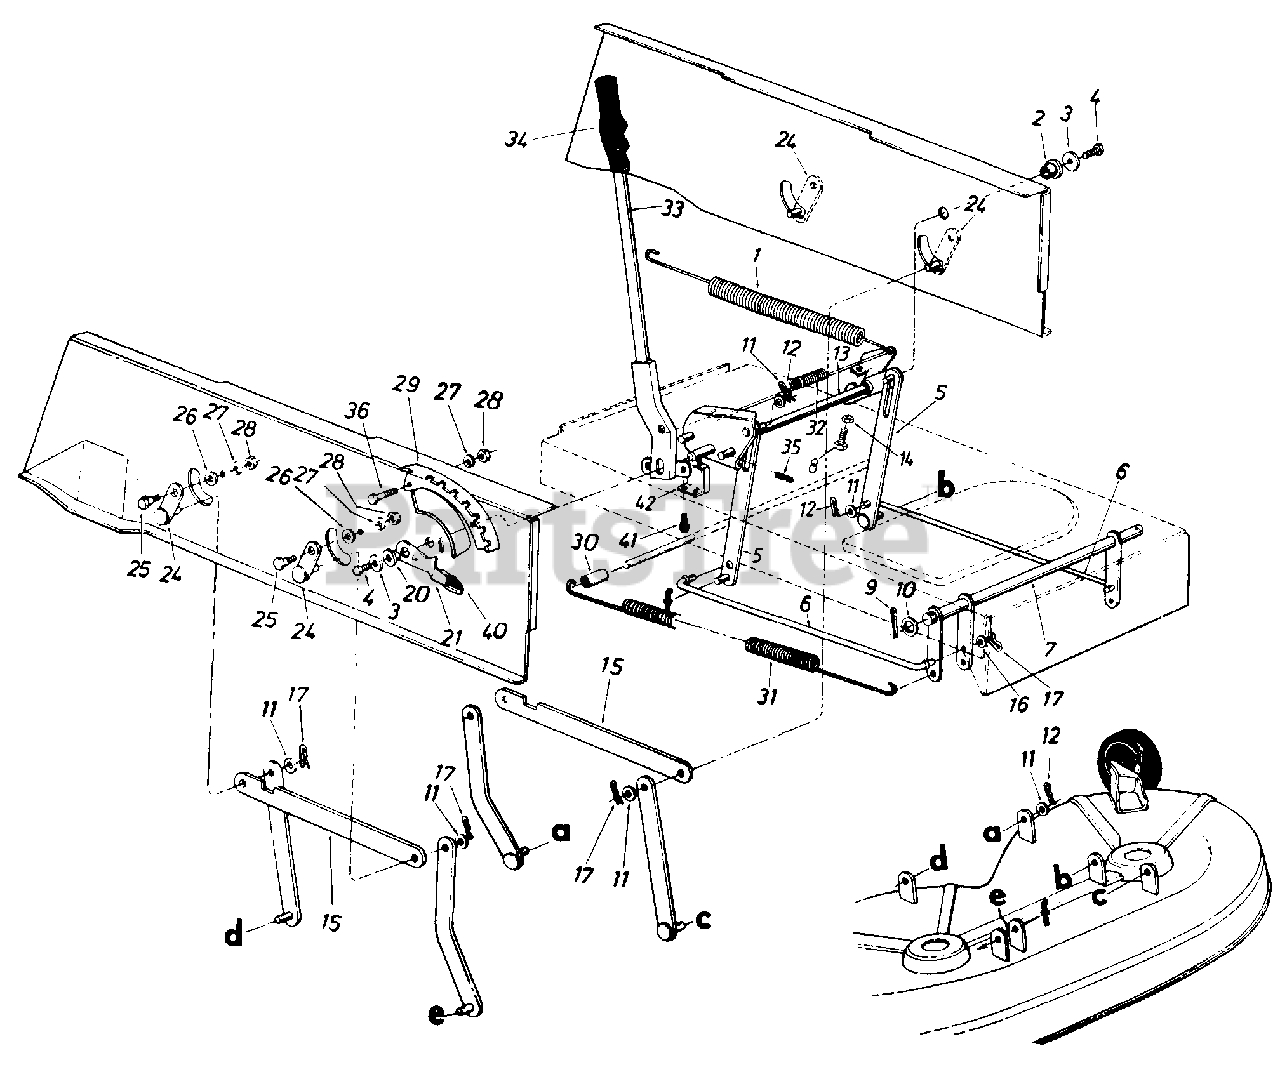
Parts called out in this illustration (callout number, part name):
1	Extension Spring 11" Lg.
2	Flange Bearing 634" I.D.
3	Fl-Wash. .344" I.D. x 1.125"
4	Hex Wash. Hd. 5/16-18 x .62" Lg.
5	Link Deck Lift Ass'y.
6	Stabilizer Rod
7	Stabilizer Shaft Ass'y.
8	Hex Tap Scr. 5/16-18 x 1
9	Cotter Pin 1/8" Dia. x 11/4"
10	Fl-Wash. .635" I.D. x 1.12
11	Fl-Wash. .531" I.D. x .940"
12	Inter. Cotter Pin
13	Lift Shaft Ass'y.
14	Hex Jam Nut 5/16-18 Thd.
15	Connecting Rod
16	Fl-Wash. .40" I.D. x .88"
17	Inter. Cotter Pin-3/8" Rod
20	Flange Brg. .630" I.D.
21	Deck Lift-Down Stop
24	Pivot Link Ass'y.
25	Shld. Bolt .437" Dia. x .180" Lg. (5/16-18)
26	Fl-Wash. .344" I.D. x .62"
27	L-Wash. 5/16" I.D.
28	Hex Nut 5/16-18 Thd.
29	Index Brkt.
30	Spacer .523" I.D. x .640" O.D. x 1.95" Lg.
31	Ext. Spring 13.25" Lg.
32	Ext. Spring 32 Coils
33	Lift Handle Ass'y.
34	Grip
35	Intern. Cotter Pin 1/2" Dia.
36	Hex Bolt 5/16-18 x .75
40	Knob
41	Hex AB-Tap Scr. #10 x .50"
42	Safety Switch
